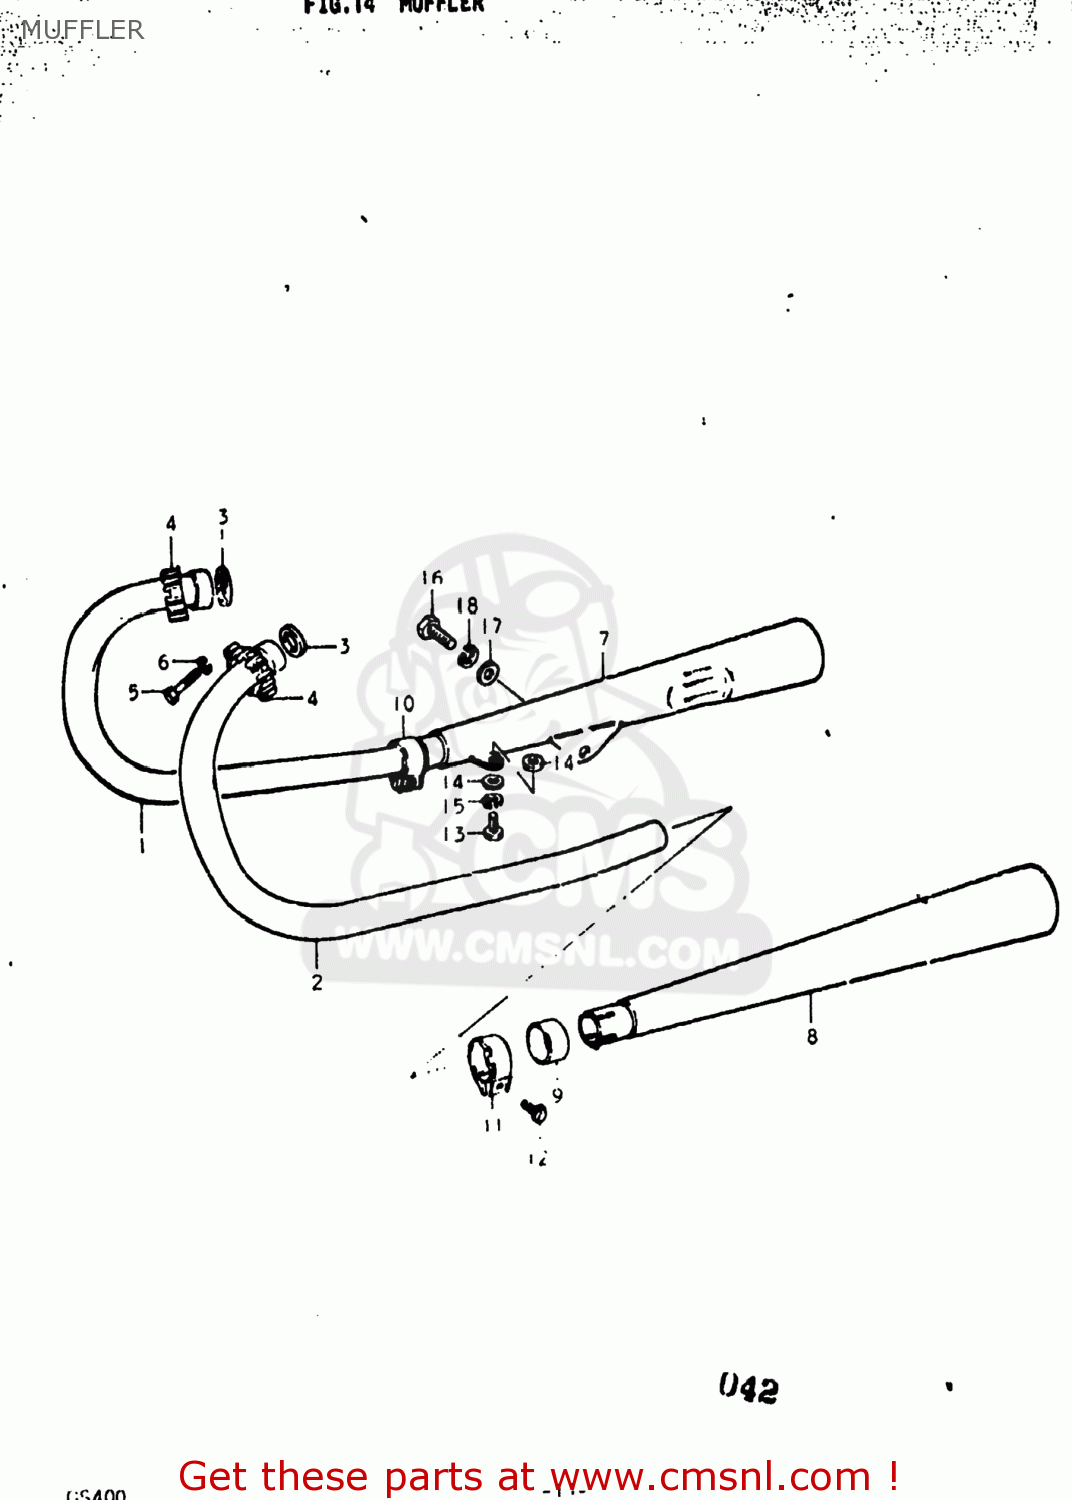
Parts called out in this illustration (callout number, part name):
1	PIPE,EXHAUST
2	PIPE,EXHAUST,LEFT
3	GASKET,EXHAUST PIPE (NAS)
4	CLAMP,EXHAUST PIPE
5	BOLT
6	LOCK WASHER
7	BODY,MUFFLER
8	BODY,MUFFLER
9	CONNECTOR,MUFFLER
10	CLAMP,MUFFLER CONNECTOR,R
11	CLAMP,MUFFLER CONNECTOR,L
12	BOLT
13	BOLT
14	WASHER (8.2X20X1.6)
15	LOCK WASHER
16	BOLT 10X25
17	WASHER
18	LOCK WASHER
